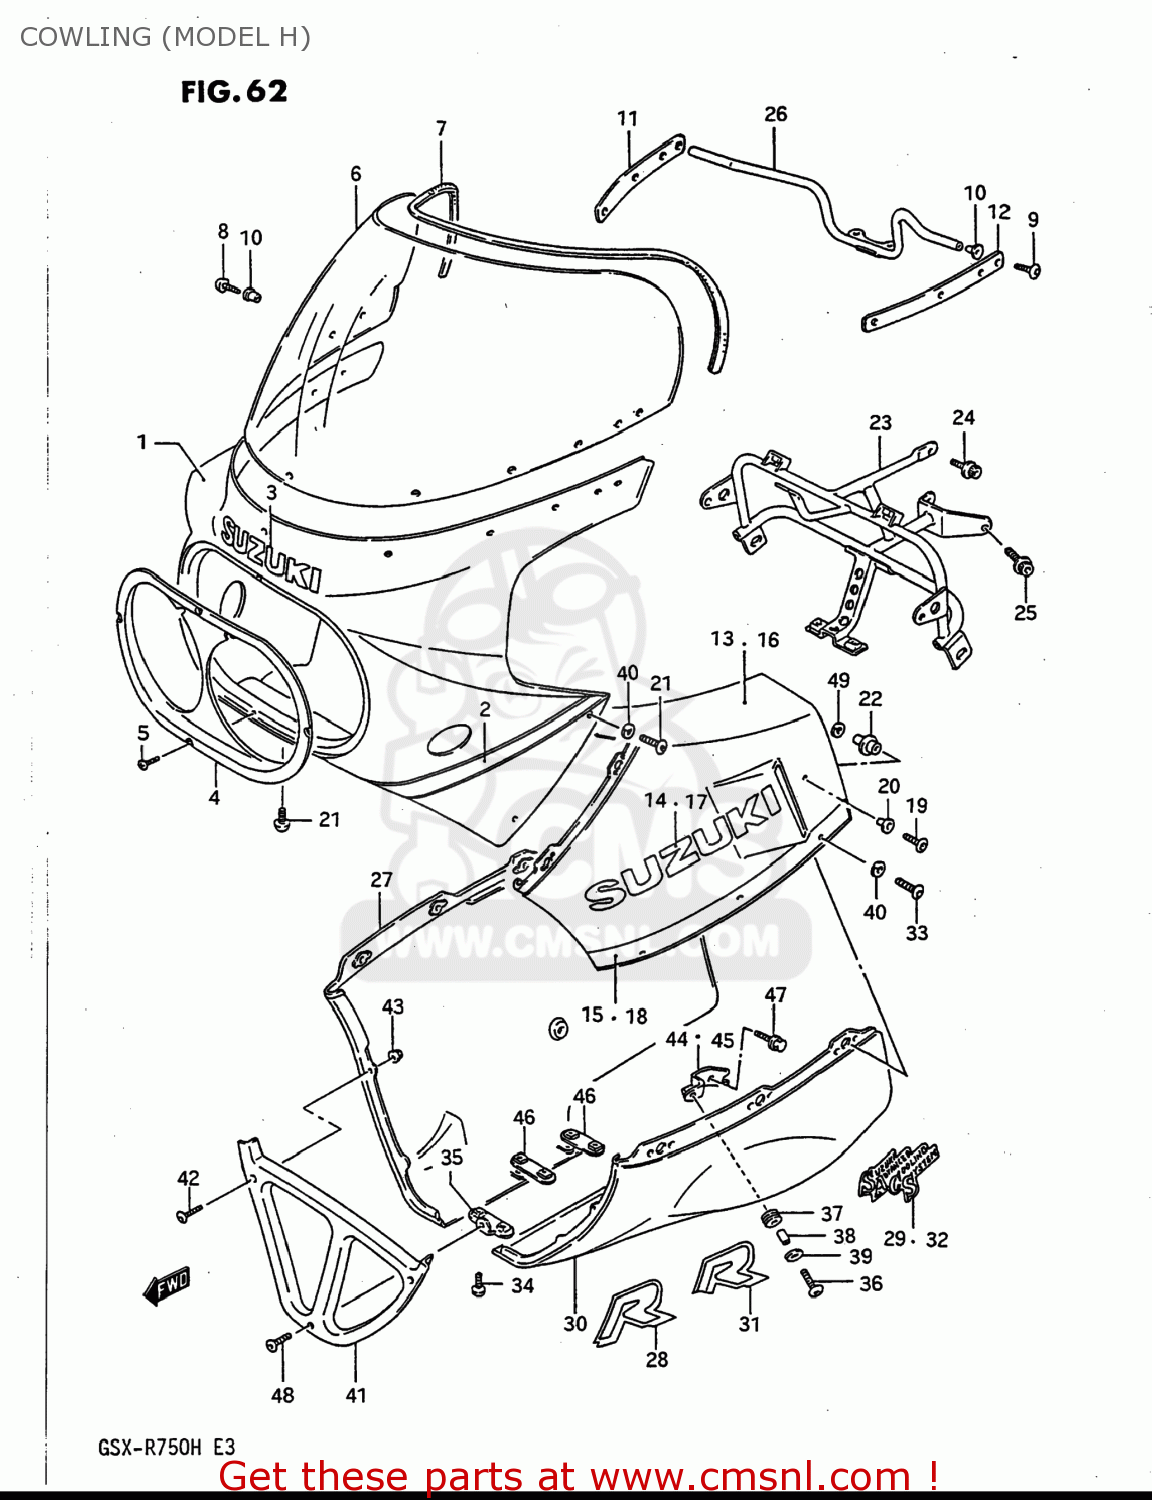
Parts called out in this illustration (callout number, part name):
1	COWLING SET
2	TAPE SET,COWLING BODY
3	EMBLEM
4	COVER,COWLING,FRONT
5	SCREW
6	WINDSCREEN
7	MOLDING,SCREEN
8	SCREW(5X14)
9	SCREW(5X18)
10	NUT,COWLING SCREEN
11	PLATE,RR VIEW MIRROR,R
12	PLATE,RR VIEW MIRROR,L
13	COVER ASSEMBLY,COWLING
14	EMBLEM
15	TAPE SET,COVER SIDE,RIGHT
16	COVER,COWLING SIDE,LEFT
17	EMBLEM
18	TAPE SET,COVER SIDE,LEFT
19	SCREW(6X12)
20	WASHER
21	SCREW(6X16)
22	CUSHION,COWLING
23	BRACE,COWLING
24	BOLT
25	BOLT
26	BRACE,COWLING BODY RR
27	COVER,COWLING,LOWER,RIGHT
28	EMBLEM
29	EMBLEM
30	COVER,COWLING,LOWER,LEFT
31	EMBLEM
32	EMBLEM
33	SCREW(6X16)
34	SCREW(6X16)
35	BRACE,COWLING LWR COVER
36	SCREW(6X20)
37	CUSHION
38	SPACER
39	WASHER(6.5X18X1)
40	WASHER
41	COVER,COWLING,LOWER,FRONT
42	SCREW(5X14)
43	NUT
44	BRACE,COWLING LWR,R
45	BRACE,COWLING LWR,L
46	BRACE,COWLING LWR COVER RR
47	BOLT
48	SCREW(6X16)
49	WASHER
